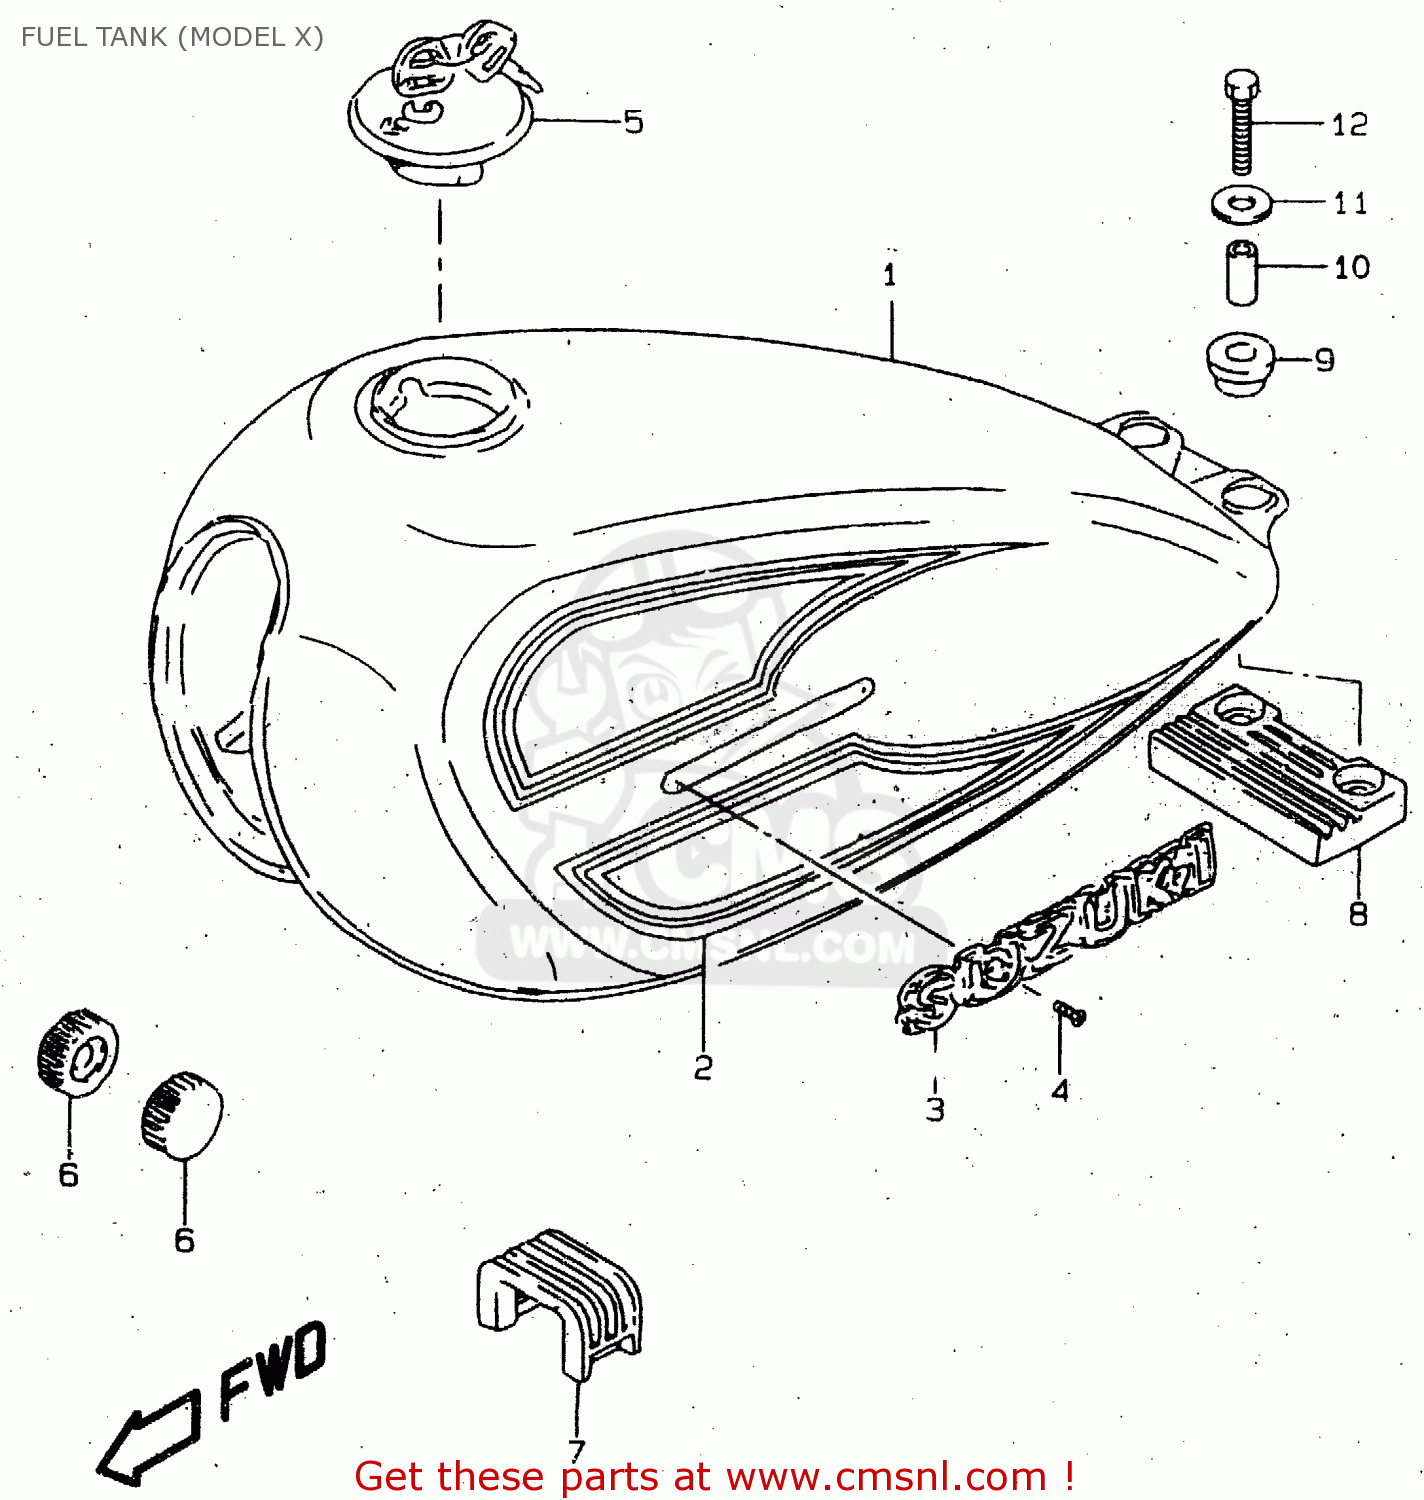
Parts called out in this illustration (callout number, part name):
1	TANK ASSY, FUEL (RED)
2	TAPE SET,FUEL TANK
3	EMBLEM,FUEL TANK
4	SCREW
5	CAP SET,FUEL TANK
6	CUSHION
7	CUSHION,FUEL TANK UPR FR
8	CUSHION,TANK RR NO.1
9	CUSHION
10	SPACER(6.5X10.5X22.5)
11	WASHER(6.5X22X1.6)
12	BOLT(6X35)
